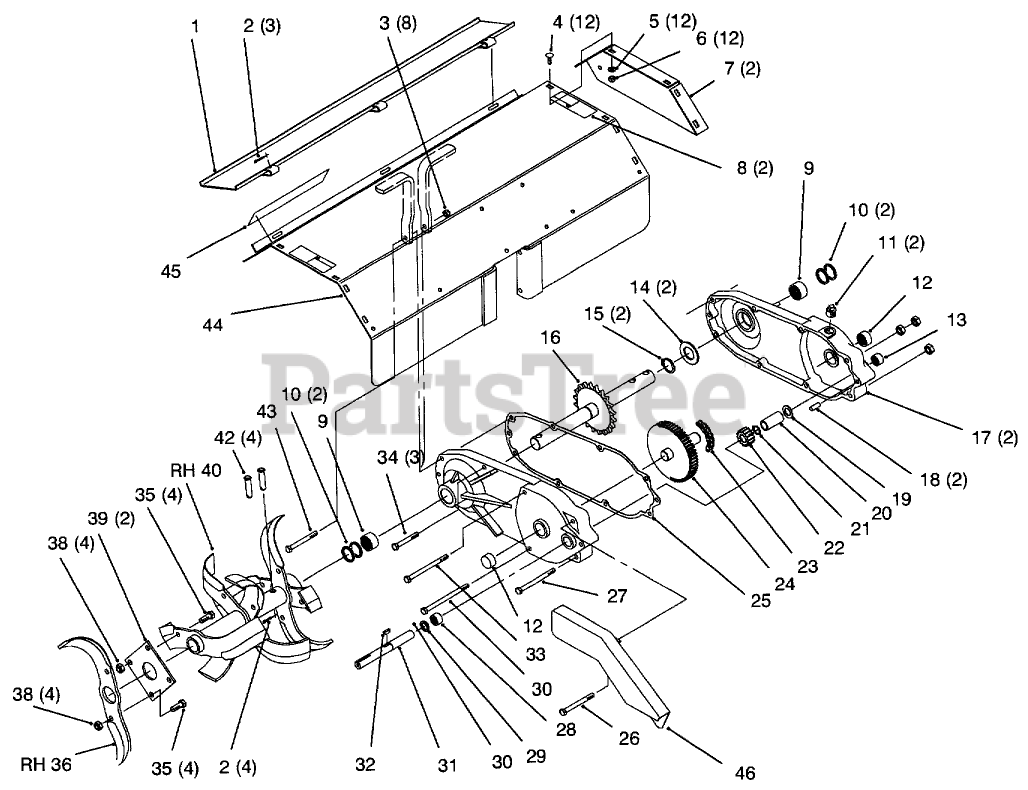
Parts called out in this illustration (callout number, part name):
1	GUARD ASM
2	PIN-COTTER
3	NUT-LOCK, NI
4	BOLT-CARR
5	WASHER-PLAIN
6	NUT-LOCK, NI
7	COVER-TINE END
8	DECAL-DANGER
9	BEARING-NEEDLE
11	PLUG-PIPE, SQH
12	BEARING-NEEDLE
13	BEARING-NEEDLE
14	WASHER
15	RING-RETAINING
16	TINE SHAFT ASM
17	GEAR CASE TILLER RED
18	PIN-ROLL
19	WASHER-THRUST
20	TUBE-SPACER
21	Ring-Snap
22	GEAR-PINION
23	CHAIN
24	GEAR AND SHAFT ASM
25	GASKET-TRANSMISSION
26	SCREW-HH
27	SCREW-HH
28	BEARING-NEEDLE
29	SEAL-OIL
30	SCREW-HH
31	SHAFT-INPUT
32	KEY-WOODRUFF
33	SCREW-HH
34	SCREW-HH
35	SCREW-HH
36	TINE-RH
37	TINE-LH
38	NUT-LOCK, NI
39	PLATE-TINE MOUNTING
40	RH TINE ASM
41	LH TINE ASM
42	PIN-CLEVIS
43	SCREW-HH
44	Shield/Decal Asm (Incl. Ref. #8)
45	DECAL-ATTACHMENT
46	Guard-Tiller
